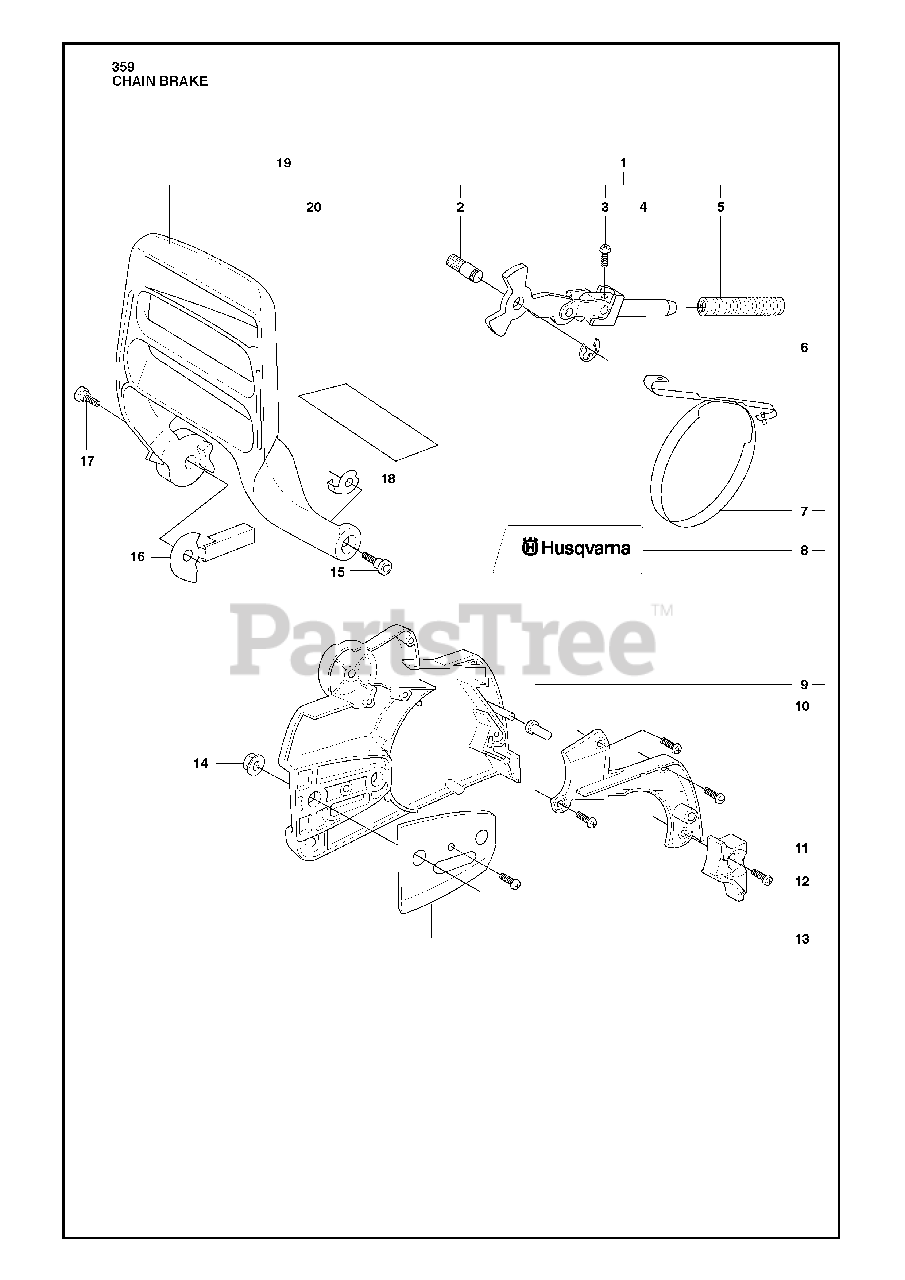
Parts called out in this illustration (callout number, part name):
1	CHAIN BRAKE
7	BRAKE BAND
14	NUT M8 FLANGE
20	PROTECTOR
